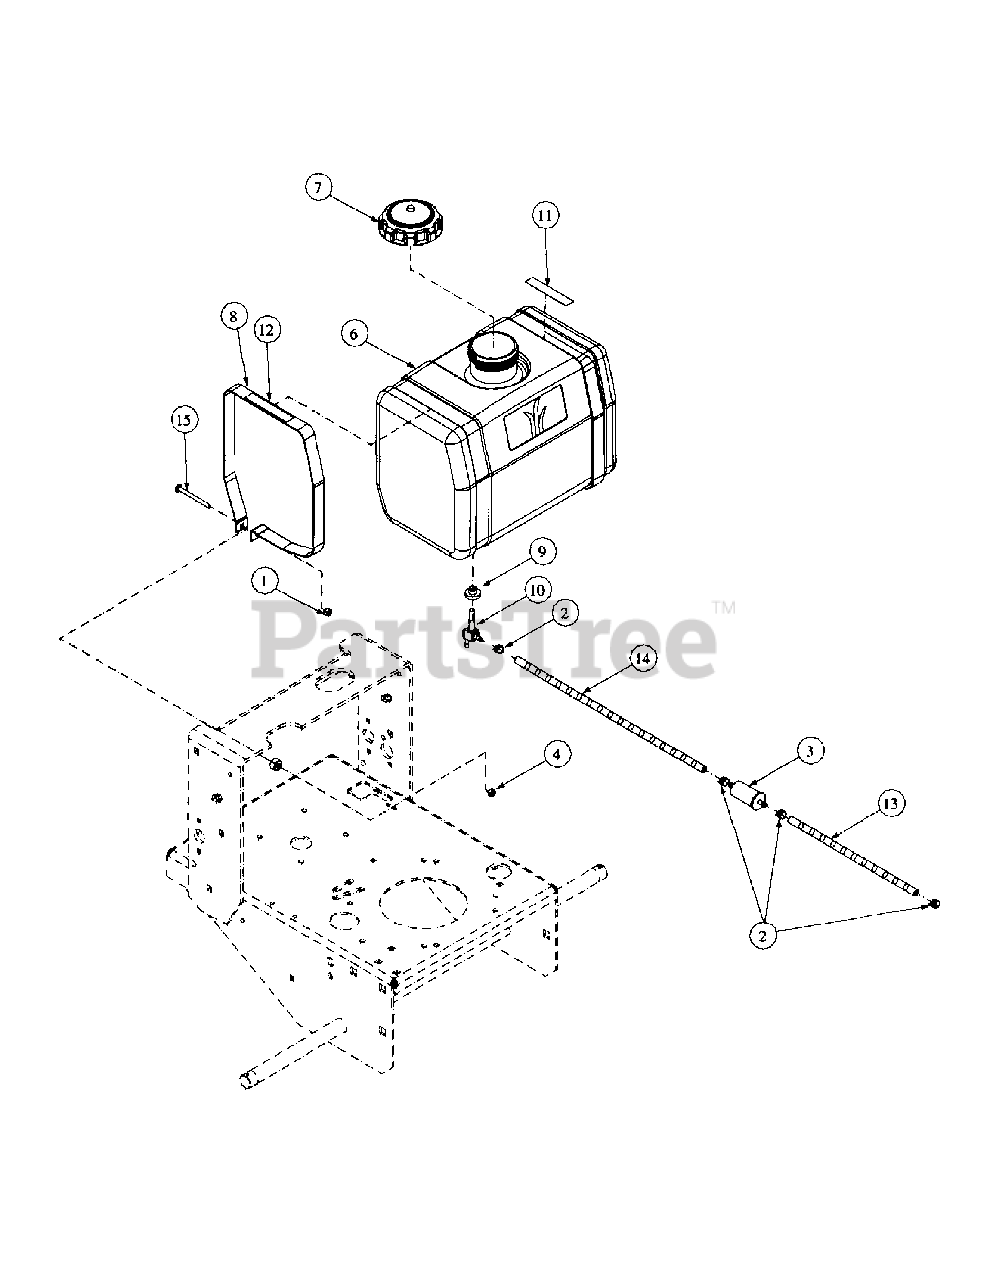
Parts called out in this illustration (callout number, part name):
1	Lock Nut, Nylon Insert, 1/4-20
2	Uni-Clamp
3	Fuel Filter
4	Nut, 1/4-20
5	Rubber Stop Pad
6	Fuel Tank
7	Fuel Cap, 3.5
8	Fuel Tank Strap
9	Grommet Fuel Tank
10	Shut Off Fuel Tank
11	Label, Mower Warning Turn Off Engine
12	Label, Mower Instruction, Fuel Valve
13	Hose Fuel, 12"
14	Hose Fuel, 18"
15	Carriage Bolt, 1/4-20 x 3.00
